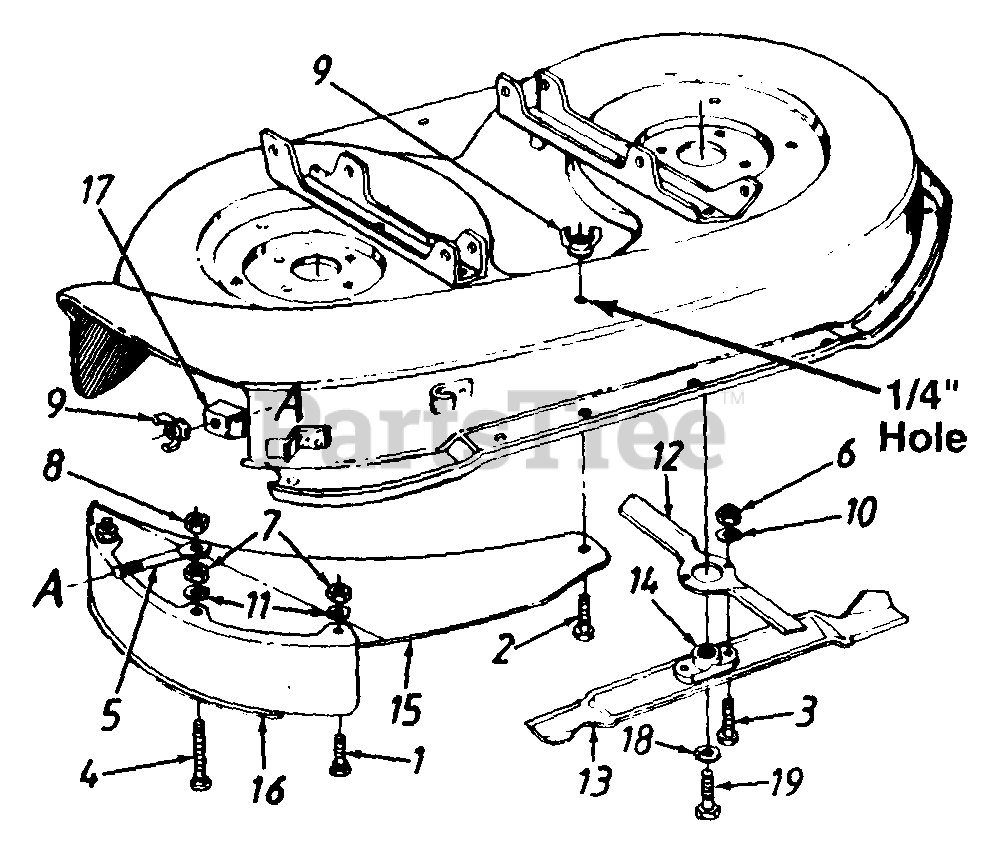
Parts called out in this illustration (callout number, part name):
1	Carriage Bolt 1/4-20 x .62" Lg.
2	Hex Bolt 1/4-20 x 1" Lg.
3	Hex Bolt 7/16-20 x 1.25" Lg.(Gr. 5)
4	Carriage Bolt 1/4-20 x 1" Lg.
5	Retaining Bolt
6	Hex Nut 7/16-20 Thd.
7	Hex Nut 1/4-20 Thd.
8	Hex L-Nut 1/4-20 Thd.
9	Wing Nut
10	L-Wash.7/16" I.D.
11	L-Wash. 1/4" I.D.
12	Mulching Blade 12.5"
13	Mulching Blade 19.38" (096)
13	Mulching Blade 21.2" (097)
14	Blade Adapter
15	Top Mulching Baffle (096)
15	Top Mulching Baffle (097)
16	Side Mulching Baffle (096)
16	Side Mulching Baffle (097)
17	Locking Bracket
18	L-Wash. 3/8" I.D.
19	Hex Bolt 3/8-24 x 1" Lg. (Gr. 8)
